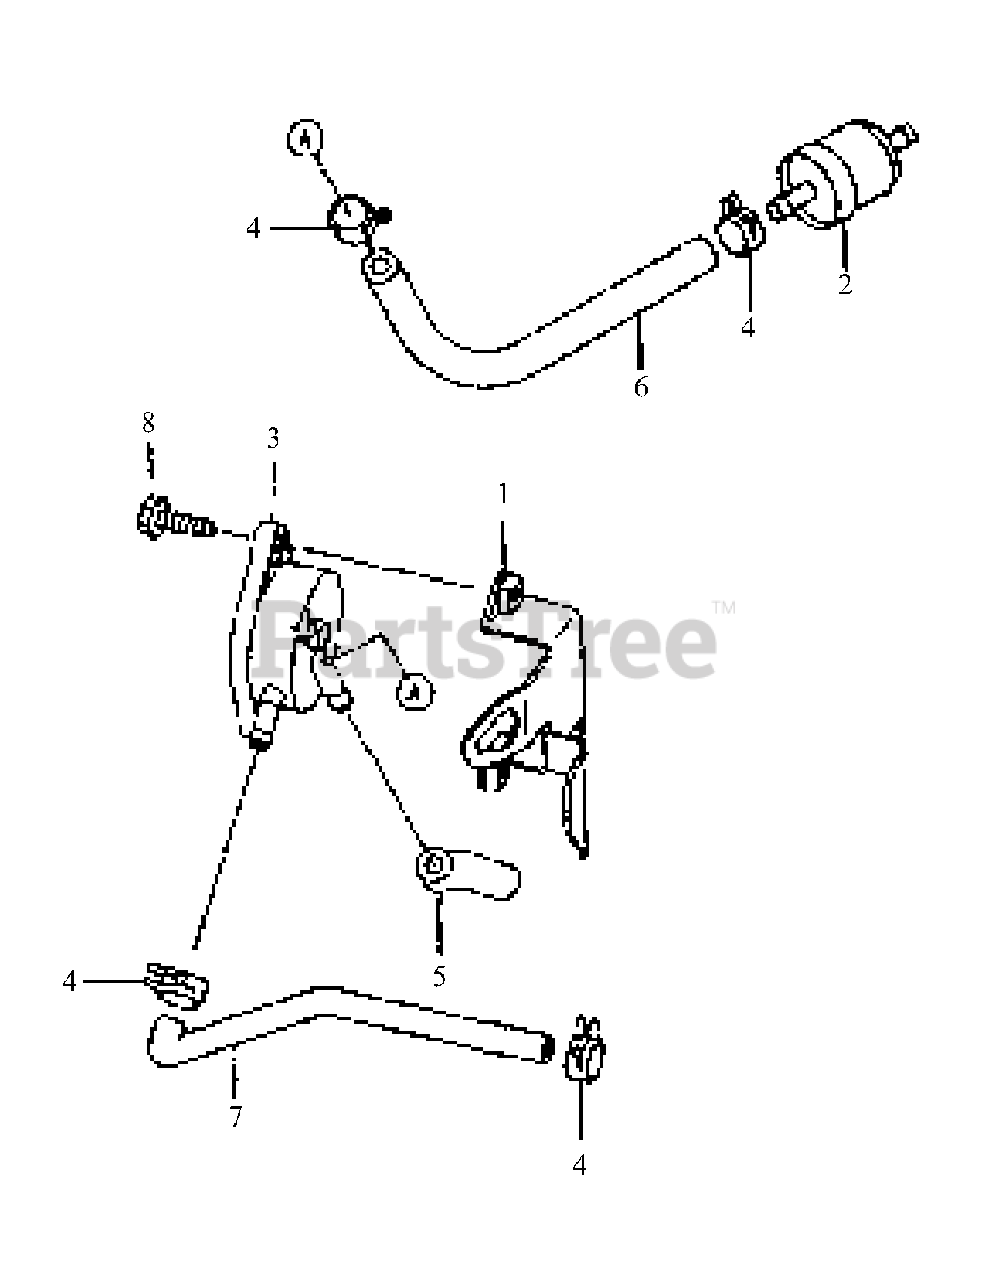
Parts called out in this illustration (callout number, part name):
2	Filter, Fuel
3	Pump, Fuel
4	Clamp
6	Tube 6.35x12.7x160
8	Bolt, Flange
